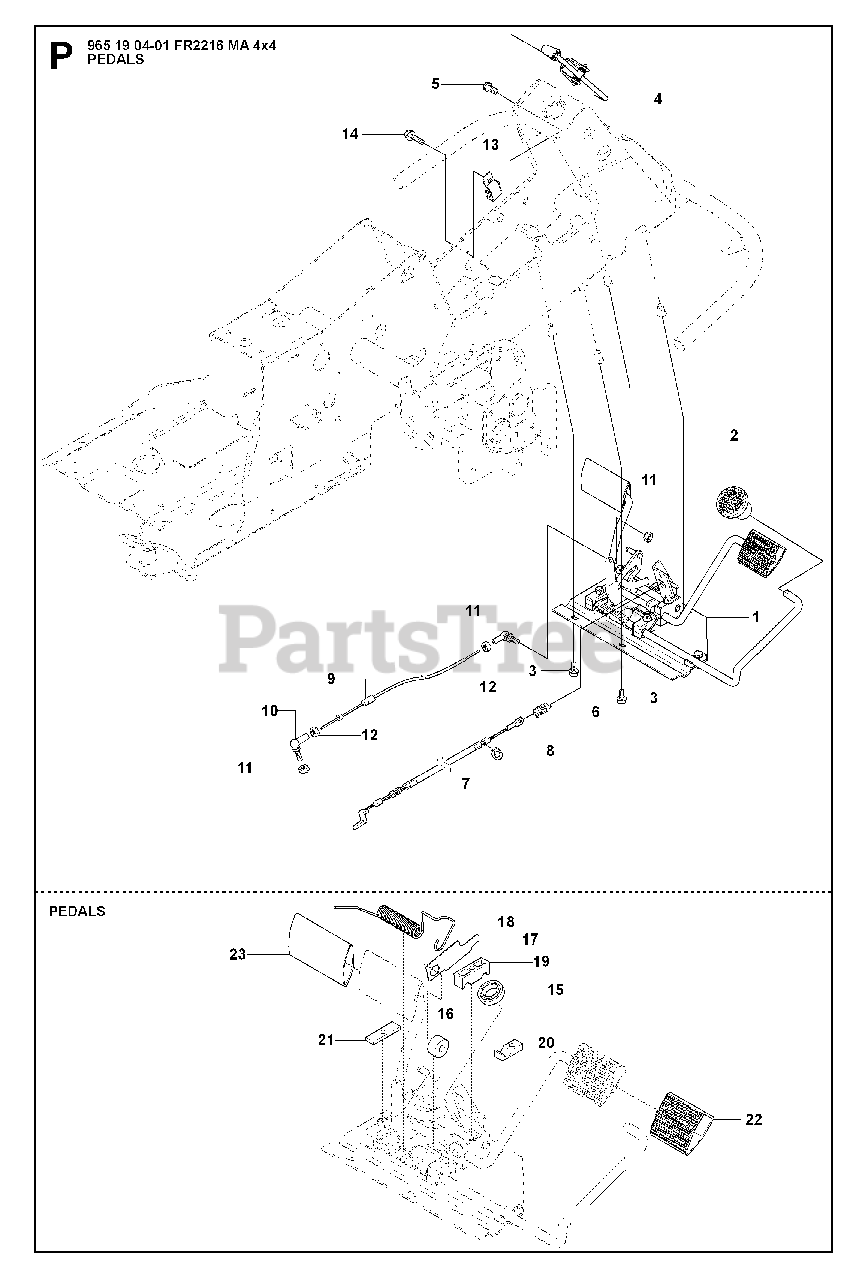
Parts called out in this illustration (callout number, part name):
1	PEDAL ASSEMBLY
2	KNOB
4	BRAKE LEVER ASSY
7	RP WIRE
9	%WIRE
10	CONNECTOR
11	LOCKNUT M5
13	BRACKET
15	BALL BEARING 6002-2RS1
16	ROLLER
17	PLATE
18	SPRING
19	PEDAL SHAFT CLAMP
20	SUPPORT
21	PLATE
22	PEDAL RUBBER
23	PEDAL RUBBER, SF
